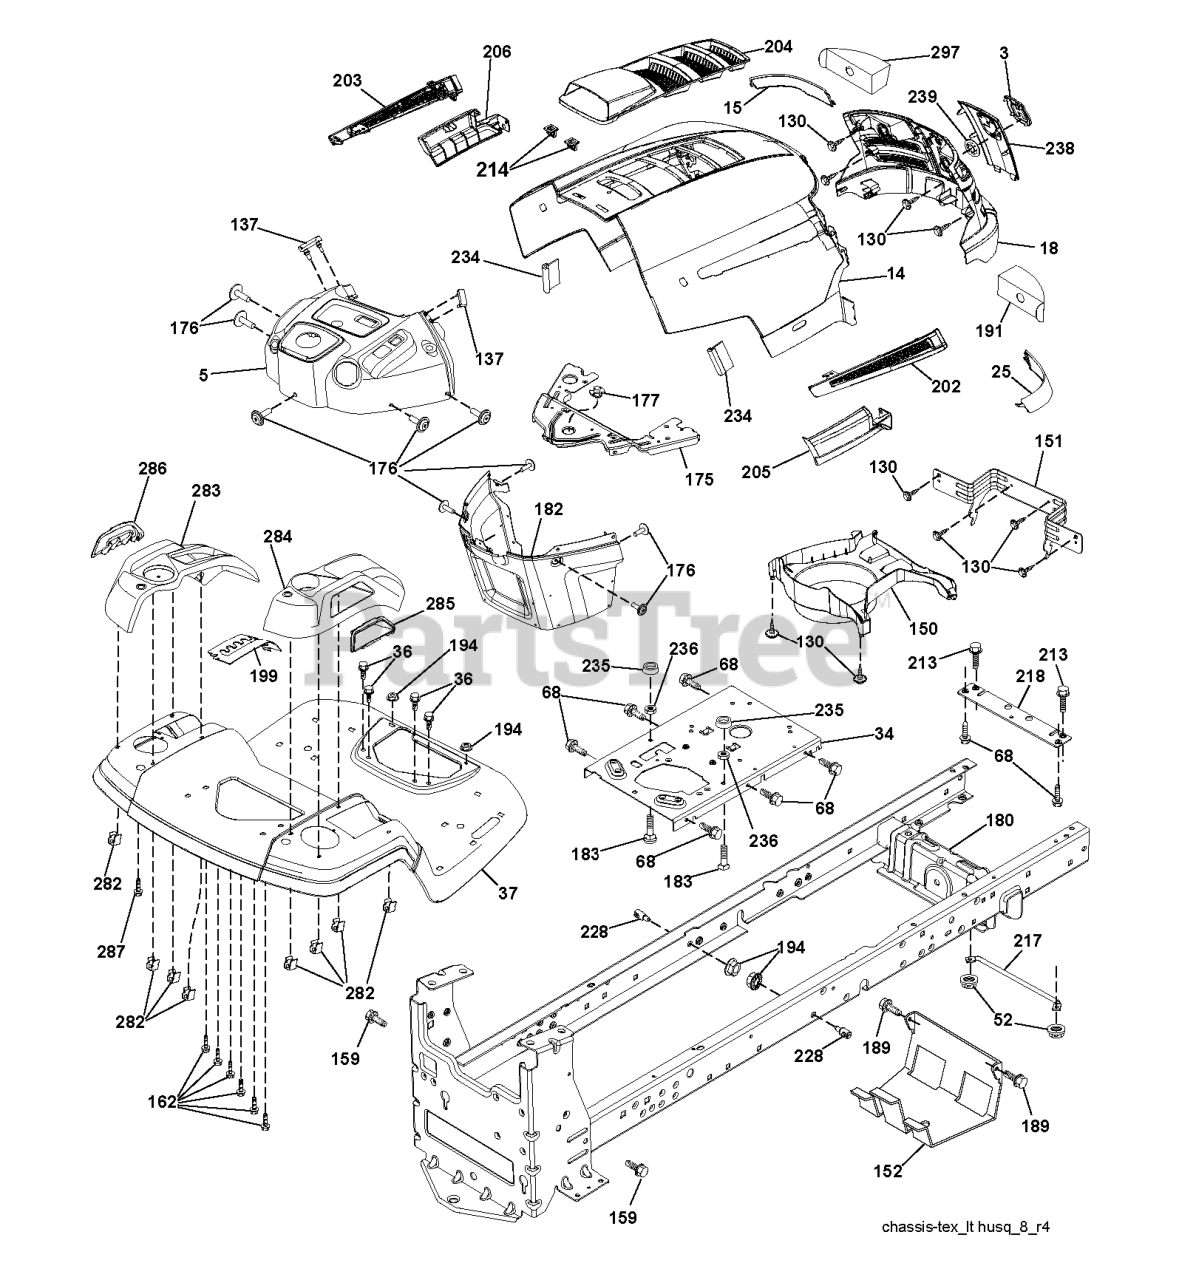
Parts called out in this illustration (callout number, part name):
3	RP LOGO
5	DASH
14	HOOD.HUSQVARNA.LT.ORANGE
15	LENS.HUSQVARNA LT.LH
18	GRILLE.SVC.HUSQVARNA.LT.GREY
25	LENS.HUSQVARNA LT.RH
34	PLATE.ENGINE.WELDED.CHASSIS
36	SCREW 5/16"
37	FENDER.TLT.FS.W/CUPHLD.ORANGE
52	LOCKNUT
68	Screw 5/16-18 x 1/2 Hex, Self Tapping 5/16-18 x 1/2
130	SCREW.#10 X 0.750.BOS
137	BUMPER DASH
151	BRACKET PIVOT
152	SHIELD.BROWNING.W/TEX
159	SCREW, 3/8-16X3/4
162	SCREW.HI-LO.CONSOLE
175	CROSSMEMBER
176	SCREW.#10-24X5/8.RN.QU
177	BUSHING STEERING
180	CHASSIS
182	DASH.LOWER.PREDATOR LT
183	BOLT.5/16-18X1-1/4 FULL THD
189	SCREW
191	INSERT.REFLECTIVE.RH.
194	NUT LOCK HEX FLANGE 5/16-18
199	PLATE.DECK.LIFT.HUSQ.LT
202	VENT SIDE HOOD RH
203	VENT SIDE HOOD LH
204	VENT TOP HOOD
205	SKIRT SIDE RH
206	SKIRT SIDE LH
213	BOLT
214	CLIP.RETAINER.TINNER.
217	ROD.PIVOT.HOOD
218	X-PIECE.HOOD.STOP.NON/
228	STUD.FASTNER.W/ANTI-ROTATE
234	BUMPER.HOOD.TEX.HUSQVARNA
235	SPACER FENDER
236	NUT.CENTERLOCK.5/16-
238	TRIM
282	CLIP.RETAINER.CONSOLE.LT.HUSQ
283	CONSOLE.DECK.LIFT.HUSQ.N/FR.GR
284	CONSOLE.CNTRL.
285	CONSOLE INSERT RH
286	CONSOLE.INSRT.LH.HUSQ.LT.BLACK
287	SCREW 1/4X20
297	INSERT REFLECTIVE
